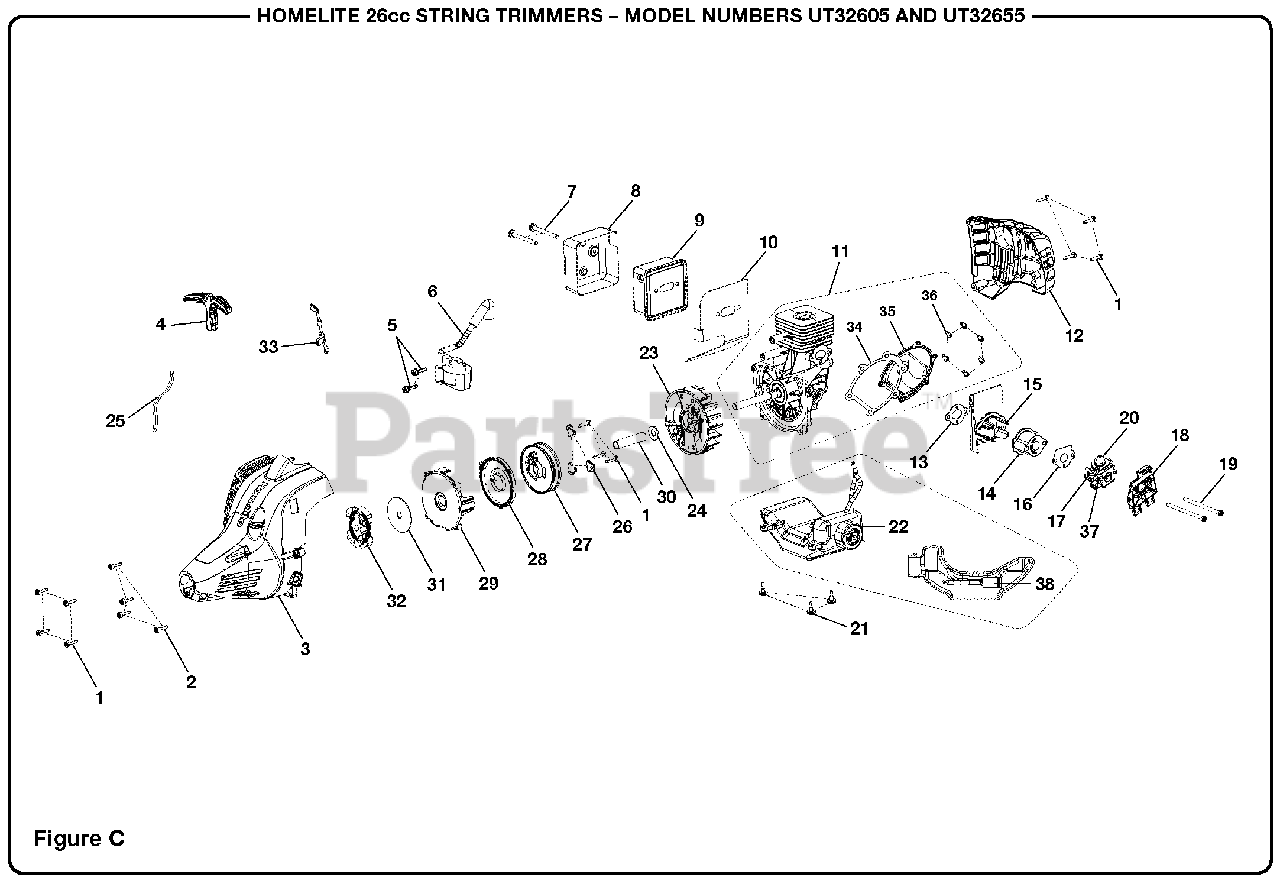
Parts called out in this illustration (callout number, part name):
1	Screw (M4 x 18 mm)
2	Screw (M4 x 16 mm)
3	Front Housing Assembly
4	Pulley Handle
5	Screw (M4 x 19 mm)
6	Ignition Module
7	Screw (10-24 x 2-3/16 in.)
8	Heat Shield
9	Muffler Assembly
10	Muffler Gasket
11	Short Block Assembly
12	Rear Housing
13	Intake Gasket
15	Heat Dam Deflector
16	Carburetor Gasket
17	Carburetor Assembly
18	Air Box Base
19	Screw (M5 x 79 mm)
20	Primer Bulb
21	Screw (M4 x 10 mm Shoulder)
22	Fuel Tank Assembly w/Cap
23	Flywheel Assembly
24	Washer
25	Starter Rope (42 in.)
26	Pulley Retainer
27	Starter Pulley Assembly
28	Spring & Container Assembly
29	Starter Housing
30	Spacer Tube
31	Clutch Washer
32	Clutch Assembly
33	Lead Assembly
34	Gasket
35	Crankcase Cover
36	Screw (M4 x 12 mm)
37	Choke Lever
38	Fuel Filter
